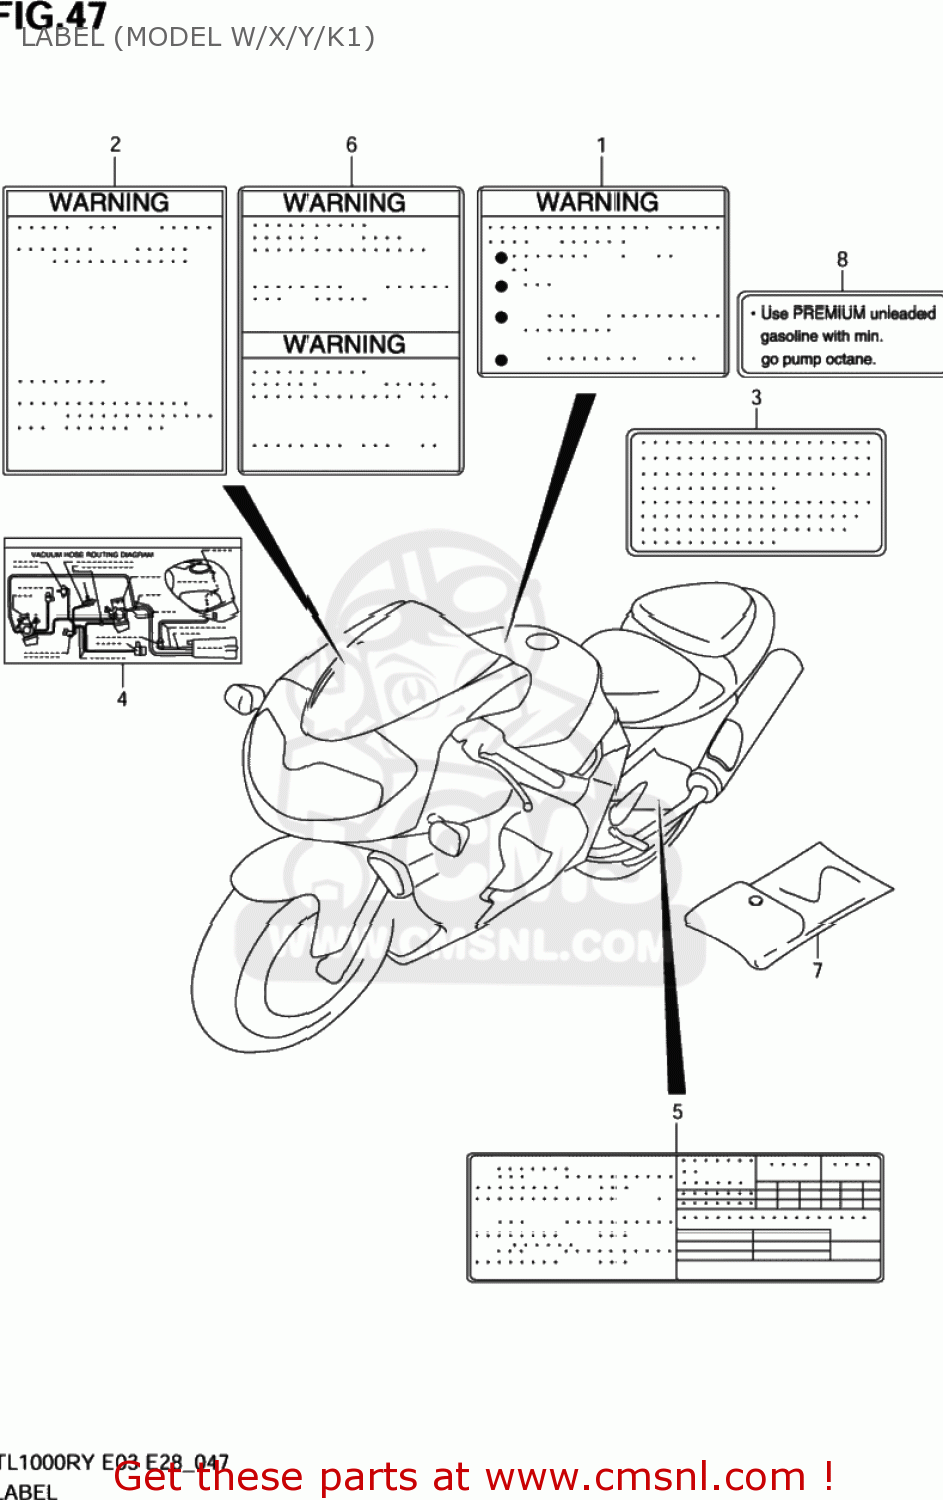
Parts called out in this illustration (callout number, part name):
1	LABEL,GENERAL WARNING
2	LABEL,WARNING SCREEN
3	LABEL (MANUAL NOTICE)
4	LABEL,VACUUM HOSE ROUTING
5	LABEL,TIRE INFORMATION
6	LABEL,WARNING STEERING
7	BAG COMP,OWNERS MANUAL
8	LABEL,FUEL INF
9	MANUAL,OWNER'S TL1000RW
